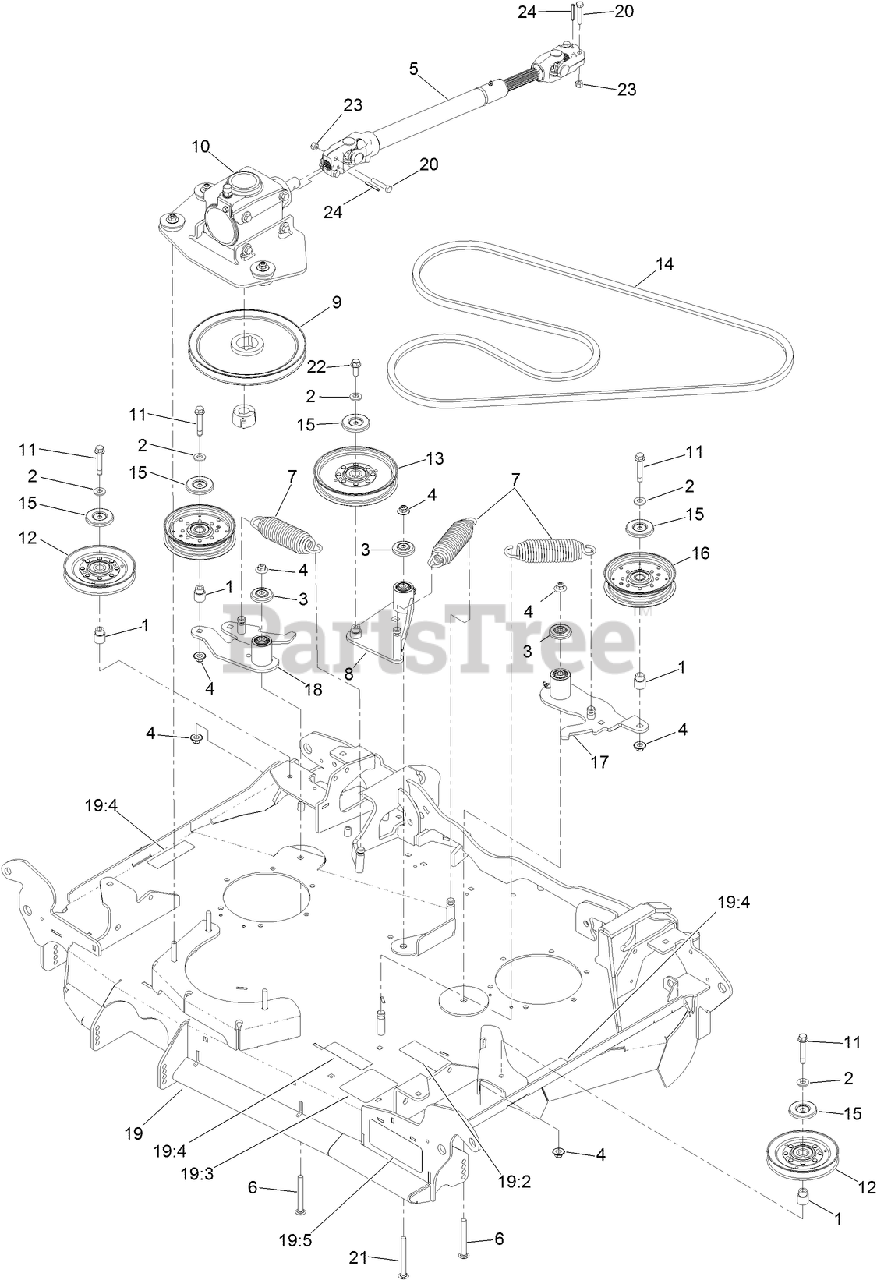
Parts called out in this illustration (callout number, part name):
1	BUSHING-IDLER
2	WASHER-BELLEVILLE
3	GUARD-TOP
4	NUT-FLANGE, NI
5	DRIVESHAFT ASM
6	BOLT-SHOULDER, CARRIAGE
7	SPRING-EXTENSION
8	IDLER ARM ASM
9	PULLEY
11	SCREW-HHF W/ PATCH
12	IDLER-V
13	IDLER-PULLEY
14	V-BELT
15	SHIELD-DUST
16	PULLEY-IDLER, FLAT
17	IDLER ASM
18	IDLER ASM
19	CENTER DECK ASM
19:2	DECAL-ROUTING, BELT
19:3	DECAL-ROLLER, ANTI-SCALP
19:4	DECAL-COVER, MISSING
20	SCREW-HH
21	SCREW-CARR
22	SCREW-HHF
23	NUT-LOCK, NI
24	PIN-ROLL
